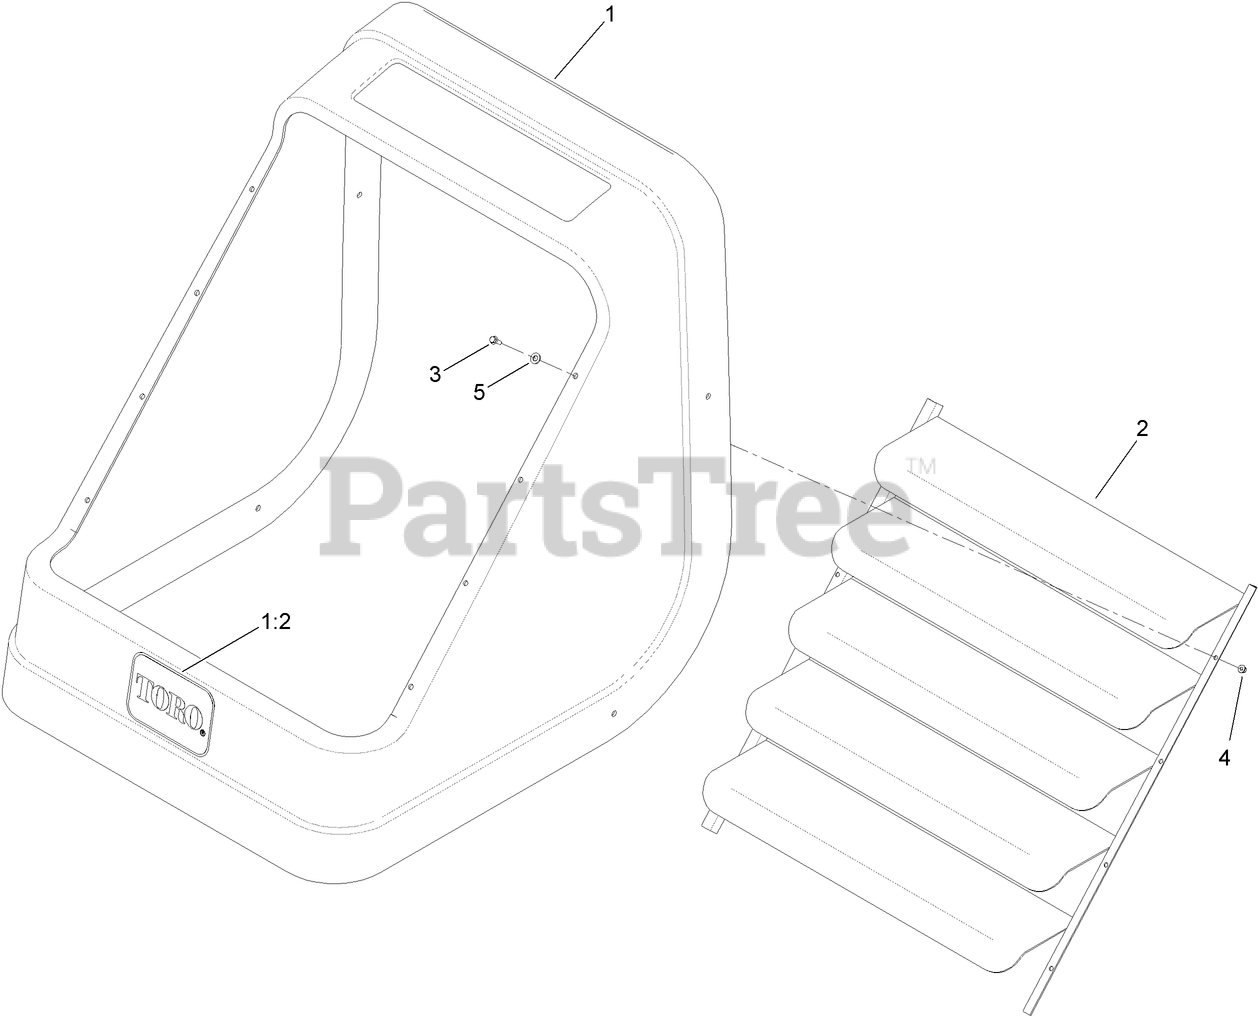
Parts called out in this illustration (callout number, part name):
1	REAR HOOD ASM
1:2	DECAL
2	LOUVER-HOOD, REAR
3	SCREW-HHF
4	NUT-HHF
5	WASHER-FLAT
